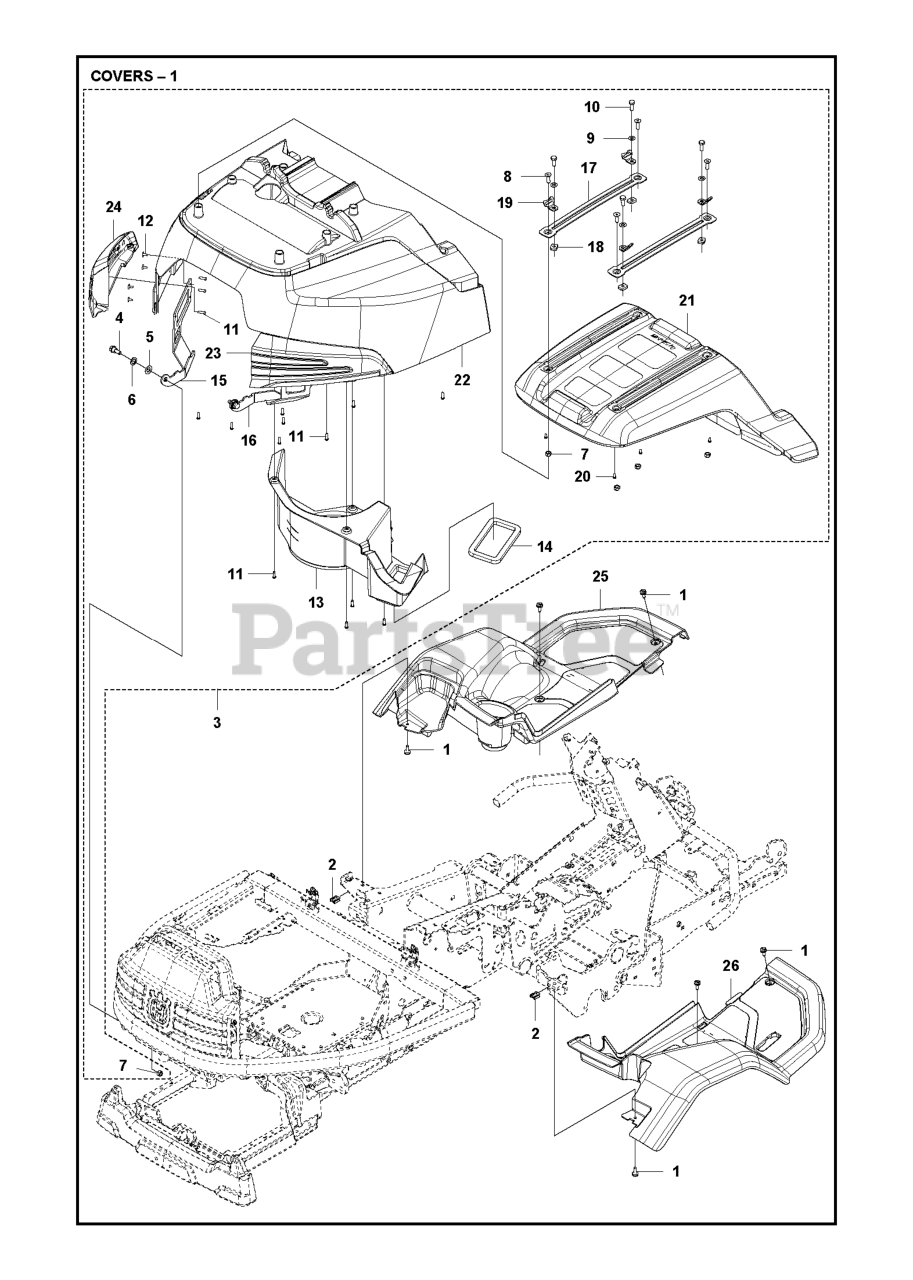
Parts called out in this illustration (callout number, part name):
5	SPRINGWASHER
7	LOCKNUT M8
11	SCREW ITXPANT T50X16 ZN/FE (A
